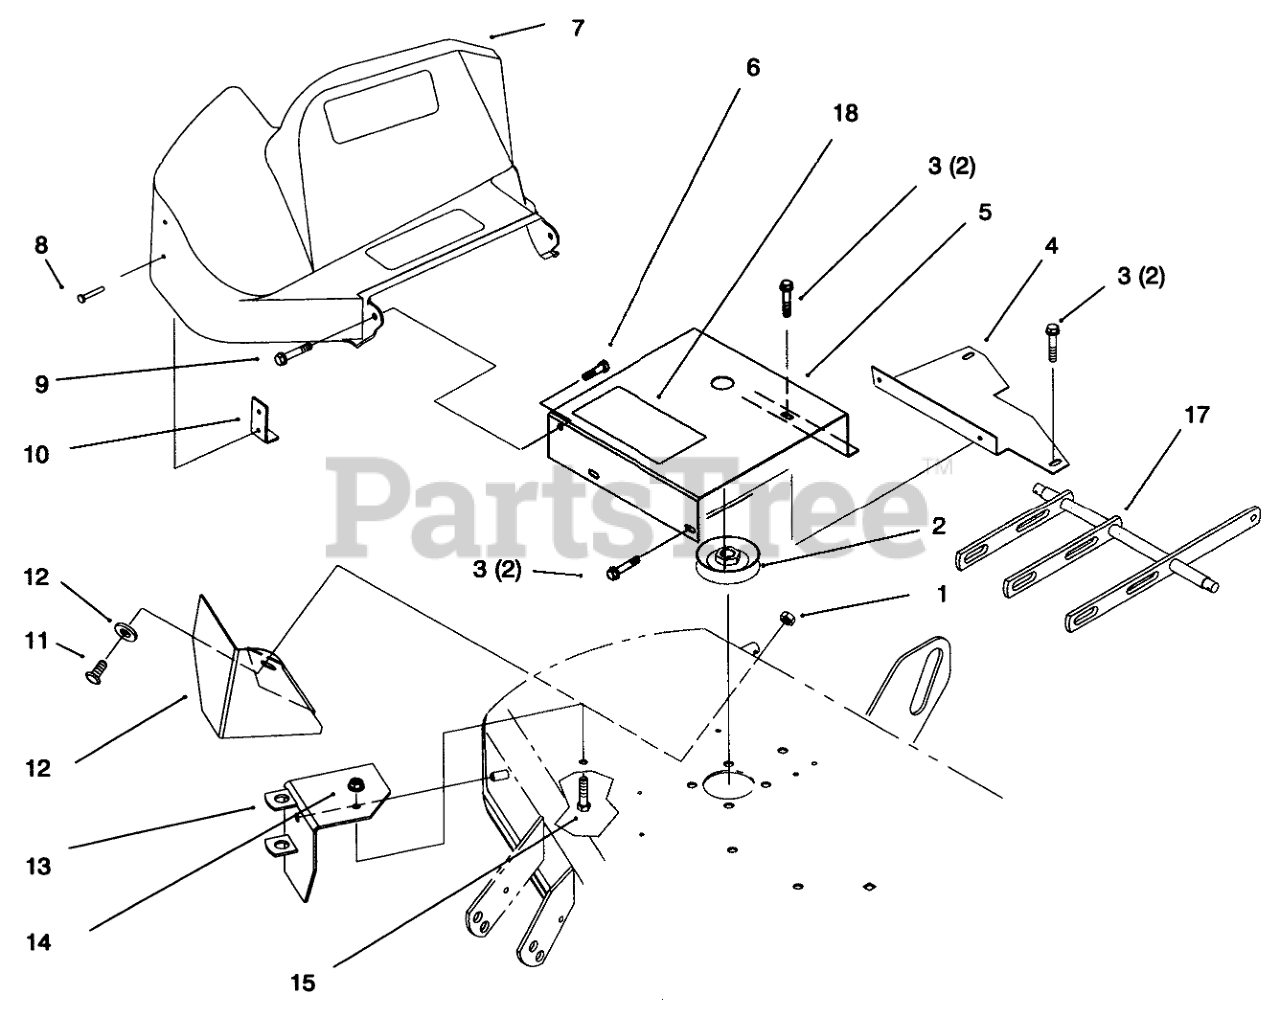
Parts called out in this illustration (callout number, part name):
1	NUT-LOCK, NI
2	PULLEY
3	SCREW-HWH
4	42" ADAPTOR SHIELD B
5	Inner Shield Asm. (Incl. Ref. #18)
6	SCREW-HH
7	SHIELD-BELT
8	RIVET-POP
9	NUT-LOCK, NI
10	BRACKET-SUPPORT, SHIELD
11	SCREW-HH
12	42" DEFLECTOR B
13	PIVOT SUPPORT ASM
14	NUT-HF
15	SCREW-HH
16	WASHER-FLAT
17	Bar-Leveler
18	DECAL-DANGER
